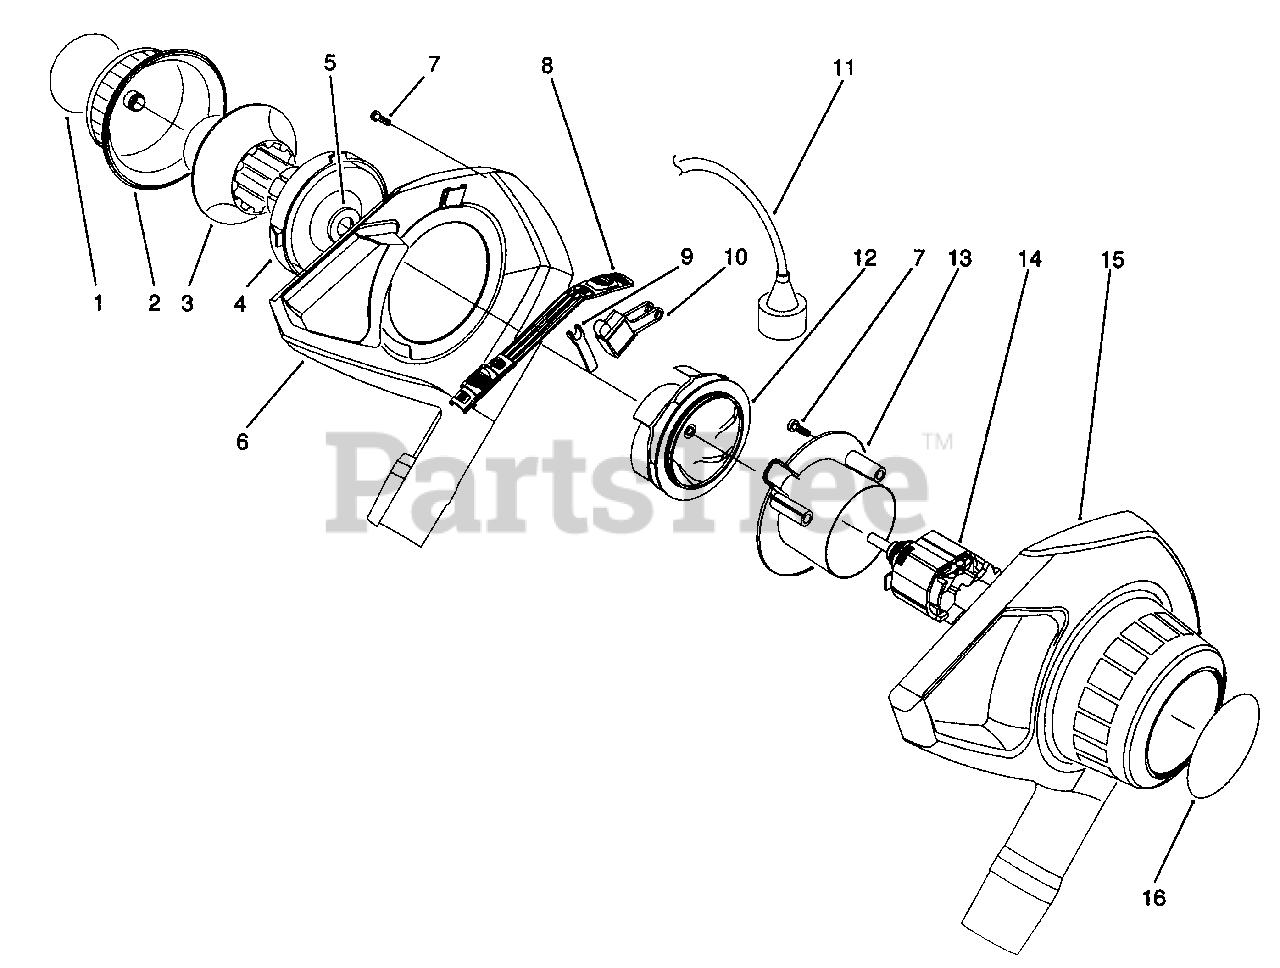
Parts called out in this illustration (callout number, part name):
1	Decal-Choke
2	Cover-Choke
3	Ring-Choke
4	Base-Choke
5	Clip-Retainer
6	Housing Assembly-R.H.
7	Screw
8	Bar-Switch
9	Lever-Actuating
10	Switch
11	Cord-Power
12	Impeller Assembly
13	Plate-Retaining
14	Motor
15	Housing-L.H.
16	Decal-Motor Cover
